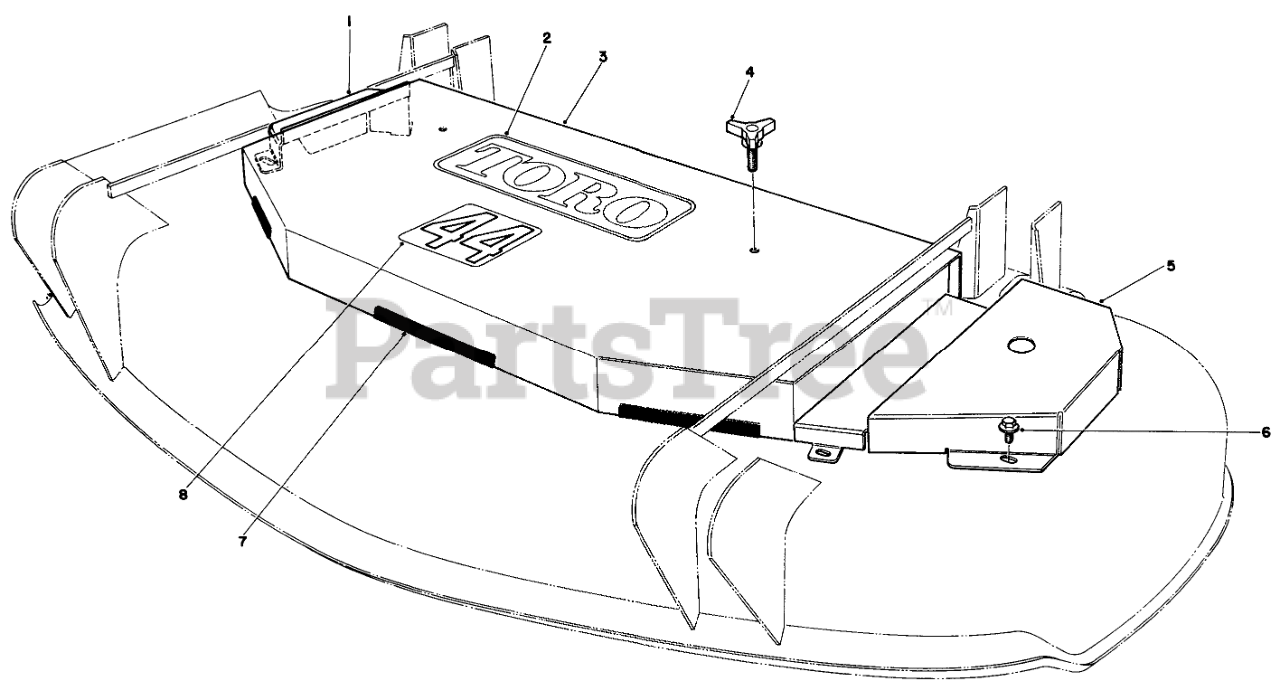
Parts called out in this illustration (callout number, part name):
1	Cover-RH
2	Decal-Toro
3	Cover-Deck
4	Knob
5	Cover-LH
6	SCREW-HHFTF
7	TRIM-JIFFY
8	DECAL-44 INCH
